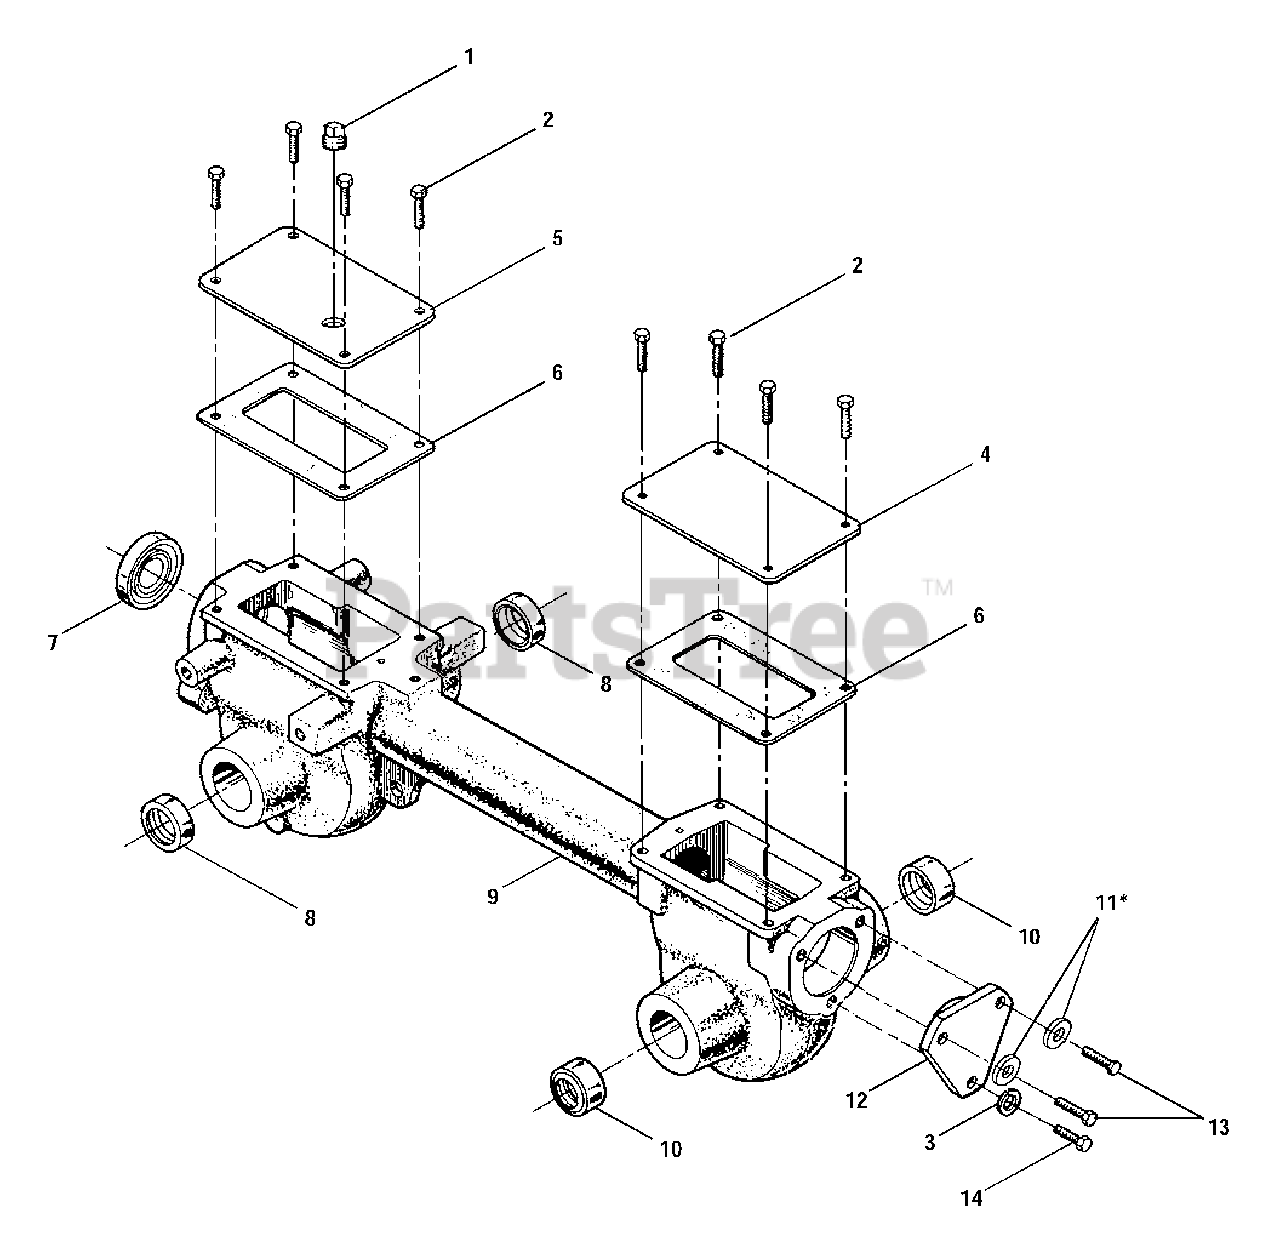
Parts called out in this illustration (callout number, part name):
1	Plug, Transmission Oil Fill
2	Hex Hd. Flange Screw, 5/16-18 x 5/8,Gr. 5
3	Lock Washer, 5/16
4	Rear Cover, Transmission
5	Front Cover, Transmission
6	Gasket, Housing Cover
7	Oil Seal, Drive Shaft
8	Oil Seal, Wheel Shaft
9	Transmission Housing Assembly
10	Oil Seal, Tine Shaft
11	Washer, Flat,.344 x.750 x.120 Included with transmission when purchased as an assembly only. Remove and discard when installing the transmission on tiller.
12	Rear Bearing Cap
13	Hex Hd. Flange Screw, 5/16-18 x 1
14	Hex Hd. Flange Screw, 5/16-18 x 3/4
